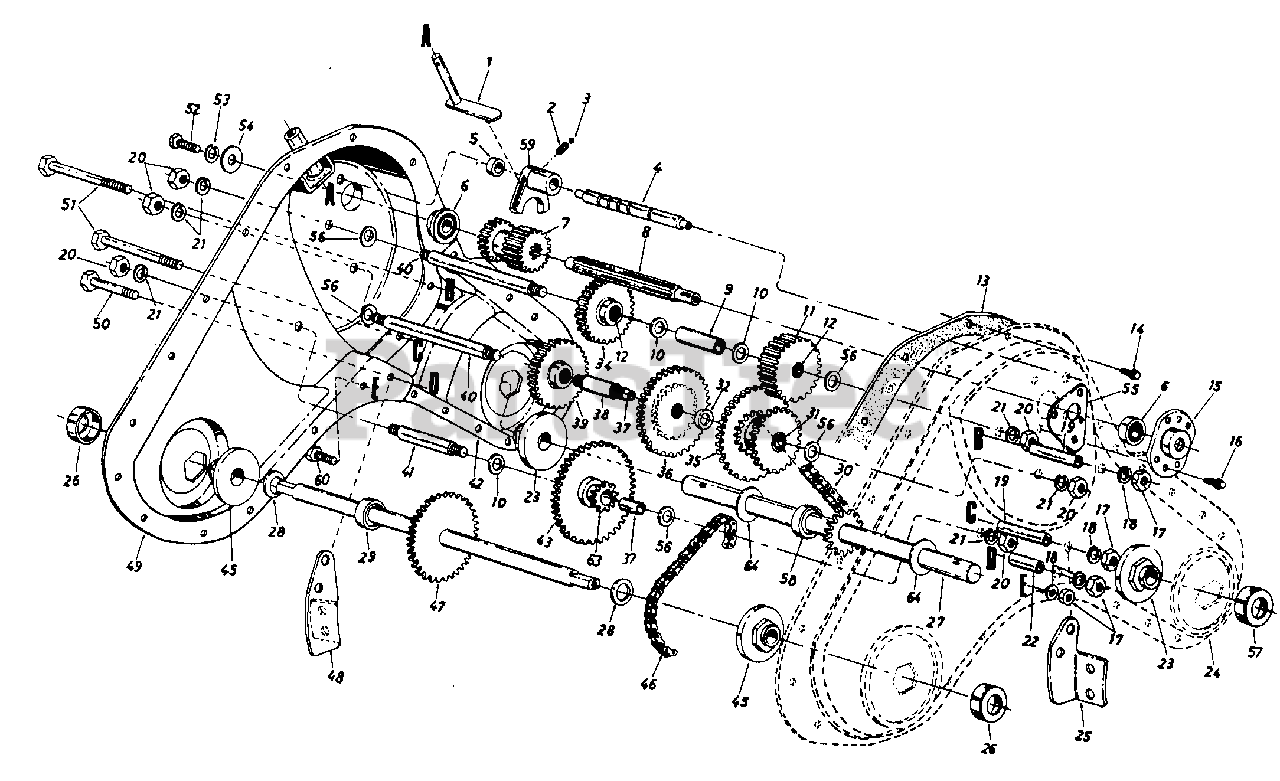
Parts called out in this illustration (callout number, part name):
1	BRACKET ASSY-SHIFT
2	SPRING-COMPRESSION
3	BALL-DETENT
4	SHAFT-DETENT
5	SPACER-.505 1D
6	BEARING-BALL
7	GEAR-SPUR-16T
8	SHAFT-INPUT
10	WASHER-FL-.640ID X 1.24OD X .06HDN
11	GEAR-SPUR-30T
12	BEARING-NEEDLE
13	GASKET
14	SCREW-HEX WASH SF TAPP
15	HOUSING-BRG
16	SCREW-HEX HD TAP 1/4-20 X 7.5
17	NUT-HEX 5/16-18
18	WASHER-LOCK-5/16
19	SPACER-1.560 1D
20	NUT-HEX 7/16-20
21	WASHER-FL
22	SPACER-1.015 1D
23	BEARING
24	HOUSING ASSY-LH
27	SHAFT ASSY-TINE
28	WASHER-FL
29	SPACER
30	#50 CHAIN 5/8 PITCH X 52L E
31	BEARING-NEEDLE
32	WASHER-FL
34	GEAR-SPUR-30T
35	GEAR-30/44T
36	GEAR-SPUR-44T
37	BEARING-SLEEVE .627 X .750 X .936
39	GEAR-SPUR-30T
40	JACKSHAFT
41	JACKSHAFT
46	#420 CHAIN-1/2 PITCH
47	SHAFT ASSY-WHEEL
51	SCREW-HEX
52	BOLT - 1/4-28 X 5/8 61.5
53	WASHER-LOCK-3/8
54	WASHER-FL
55	BRACKET-GEAR POS
56	WASHER-FL
57	COVER-DUST
58	SPACER
59	FORK-SHIFT
60	SCREW-HEX 5/16-18 X .75
63	SPROCKET ASSY-10T
64	WASHER-FL-1.03 ID X 1.62 X .03 HD
